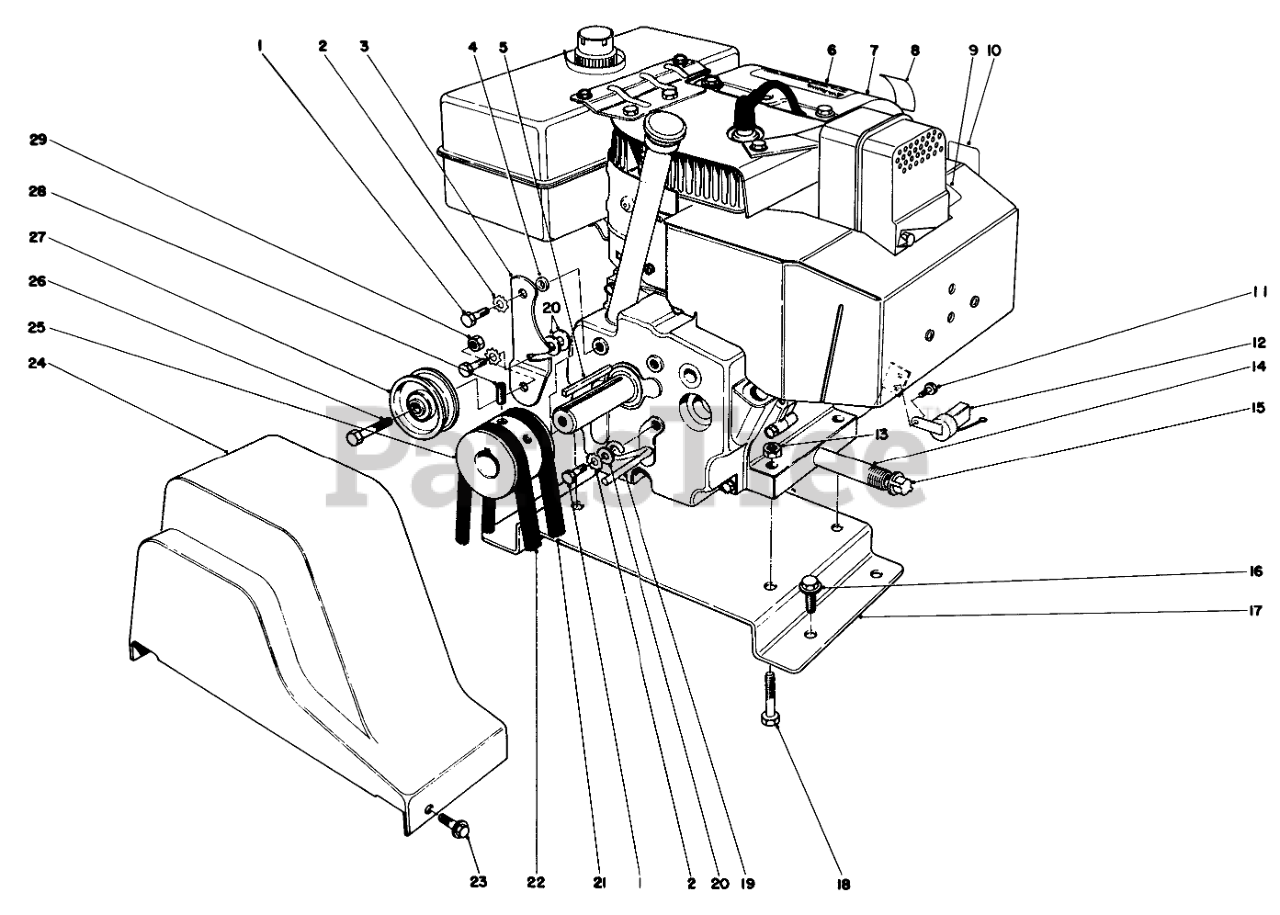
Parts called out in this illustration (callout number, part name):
1	SCREW-HH
2	WASHER-LOCK
3	ENGINE IDLER ARM
4	SPACER
6	Decal-Hazard
7	Engine
8	PRIMER DECAL
9	Decal Hot Surface Warning
10	CHOKE DECAL
11	SCREW
12	INTERLOCK MODULE
13	NUT-LOCK, NI
14	NIPPLE-PIPE
15	CAP-PIPE
16	SCREW-HHFTF
17	Plate ngine Mounting
18	SCREW-HH
19	BELT RETAINER
20	WASHER-PLAIN
21	V-BELT
22	V-BELT
23	SCREW-HWH
24	BELT GUARD
25	ENGINE PULLEY
26	SCREW-HH
27	PULLEY-IDLER
28	Screw-Set
29	NUT-HEX
